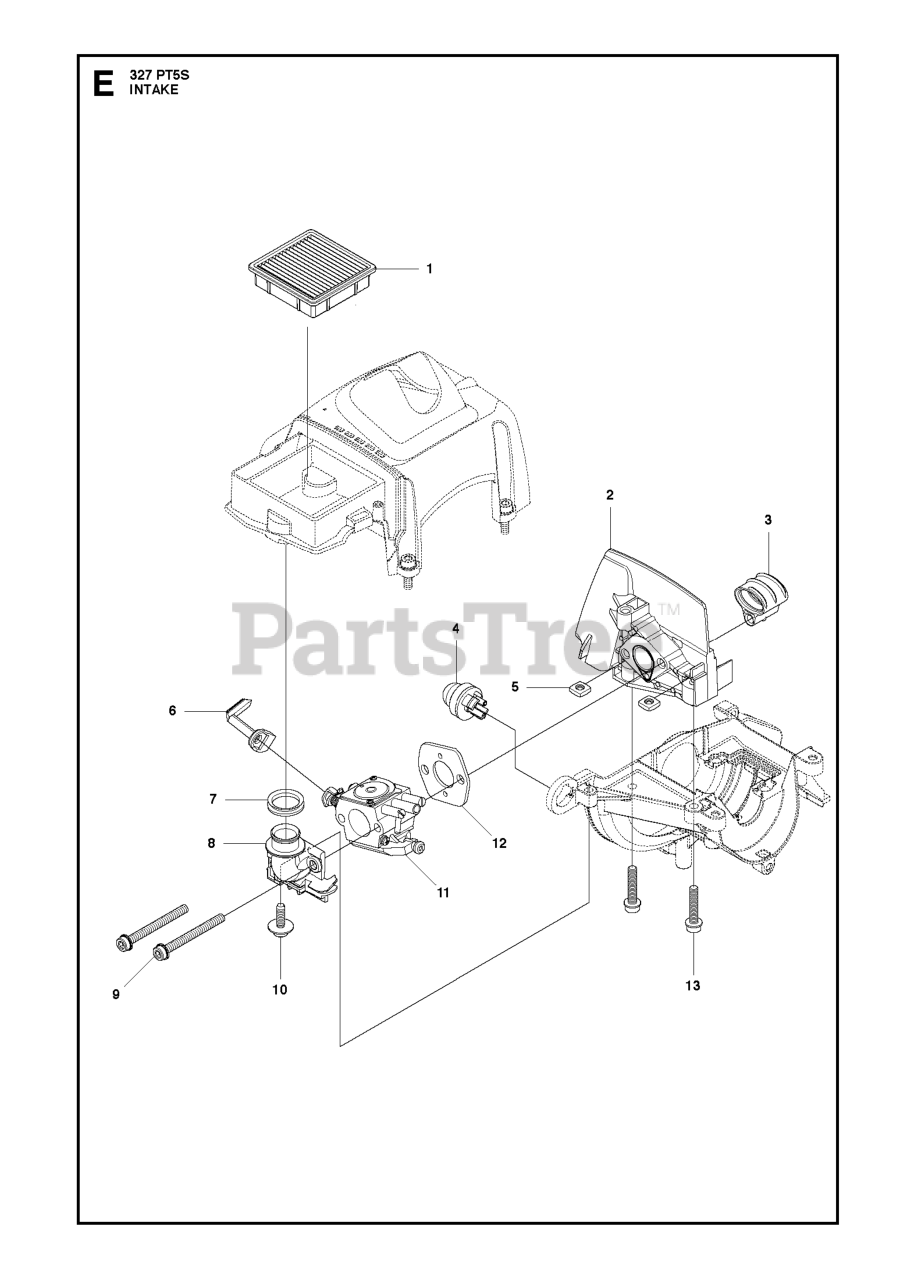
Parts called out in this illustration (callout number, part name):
4	AIR PURGE BUBBLE
6	CHOKE CONTROL
11	CARBURETOR
